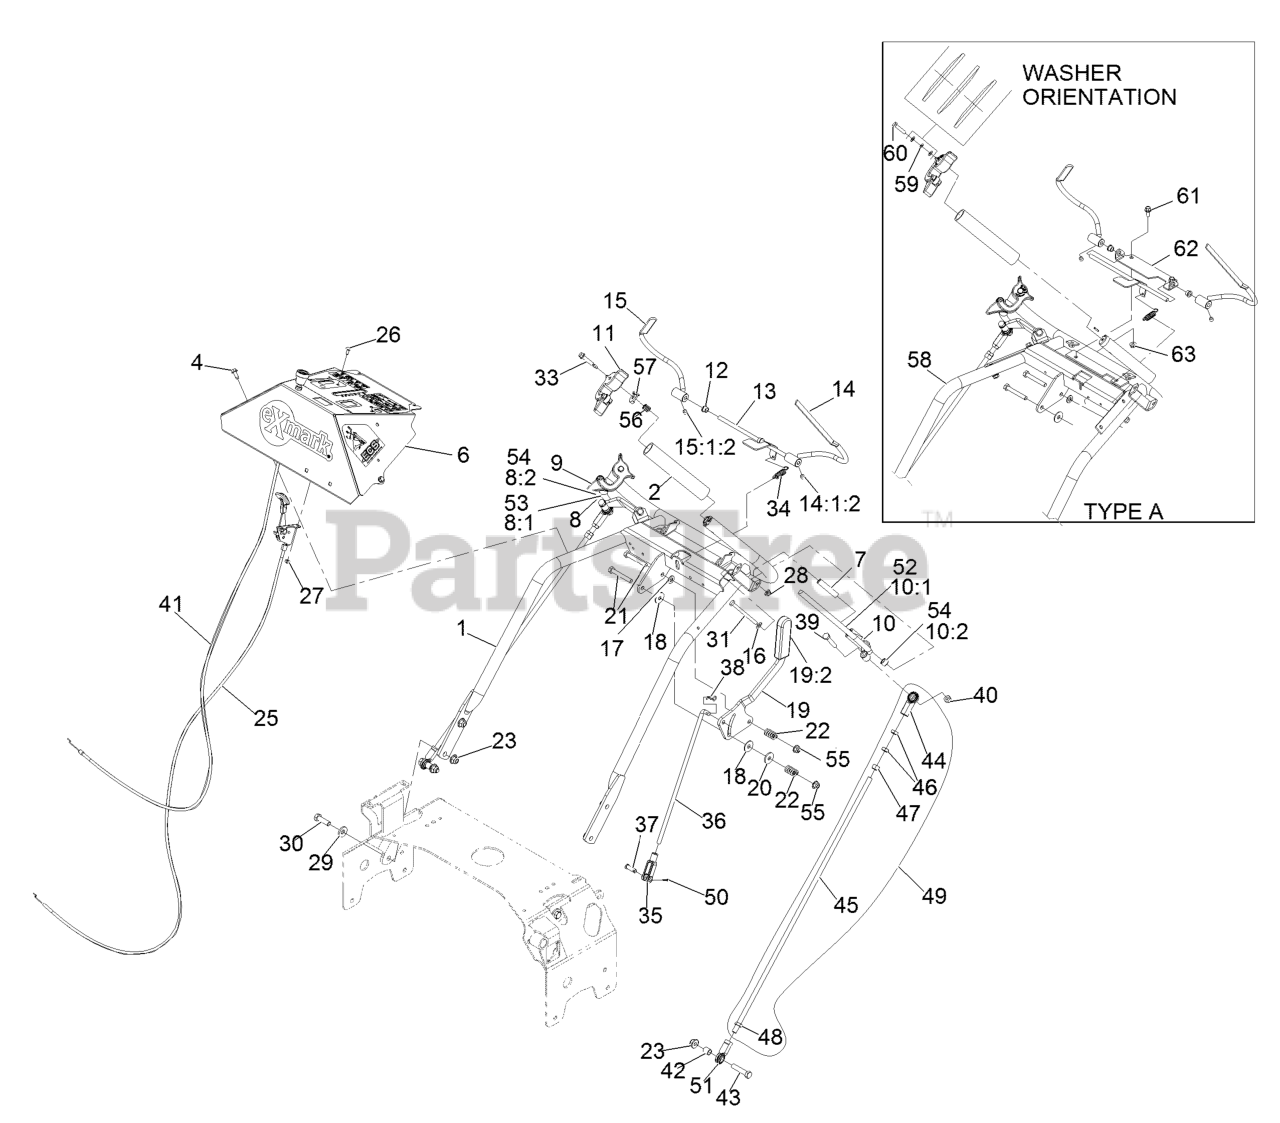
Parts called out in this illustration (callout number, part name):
1	WELD, HANDLE
2	GRIP-BAR, HANDLE
4	SCREW-HWH
6	ASM, CONSOLE W/ DECALS
7	BUSHING-LEVER, DRIVE
8	DRIVE LEVER-ASM, RH
8:1	WLD,RH DRIVE LEVER
8:2	BUSHING-SLEEVE
9	ASM,LATCH RH THUMB
10	DRIVE LEVER-ASM, LH
10:1	WLD,LH DRIVE LEVER
10:2	BUSHING-SLEEVE
11	ASM,LATCH LH THUMB
12	BUSHING-NYLON
13	WLD,OPC LEVER AXLE
14	WLD,LH OPC LEVER
14:1:2	SCREW-SET
15	WLD,RH OPC LEVER
15:1:2	SCREW-SET
16	WASHER-FLAT
17	WASHER-PLAIN
18	WASHER-FRICTION
19	LEVER, SHIFT W/GRIP
19:2	GRIP-HANDLE, STEERING
20	WASHER-FRICTION
21	SCREW-HH
22	SPRING-COMPRESSION
23	NUT-HF, NI
25	CONTROL-THROTTLE
26	BOLT-CARR
27	NUT-LOCK, NI
29	WASHER-BELLEVILLE
30	SCREW-HH
31	SCREW-HH
33	SCREW-SHOULDER
34	SPRING-EXTENSION
35	YOKE-ADJUSTABLE
36	ROD,SPEED CONTROL
37	PIN-CLEVIS
38	PIN-COTTER
39	SCREW-HH
40	NUT-LOCK, NI
41	CABLE, CHOKE
42	SPACER-TUBE, PUMP LINK
43	SCREW-HH
44	JOINT-BALL, END
45	LINK,DRIVE (PLTD)
46	NUT-HJ
47	NUT-HEX
48	NUT-HEX JAM, LH
49	DRIVE LINK ASM
50	PIN-COTTER
51	JOINT-BALL END, LH
52	WLD,LH DRIVE LEVER
53	WLD,RH DRIVE LEVER
54	BUSHING-SLEEVE
55	NUT-HF, NI
56	SPRING-TANK, FUEL
57	LATCH, ECS
58	WLD,TTH ECS HANDLE
59	WASHER-SPRING
60	SCREW-HH
61	SCREW-HEAD, FLANGE
62	BRACKET,OPC AXLE
